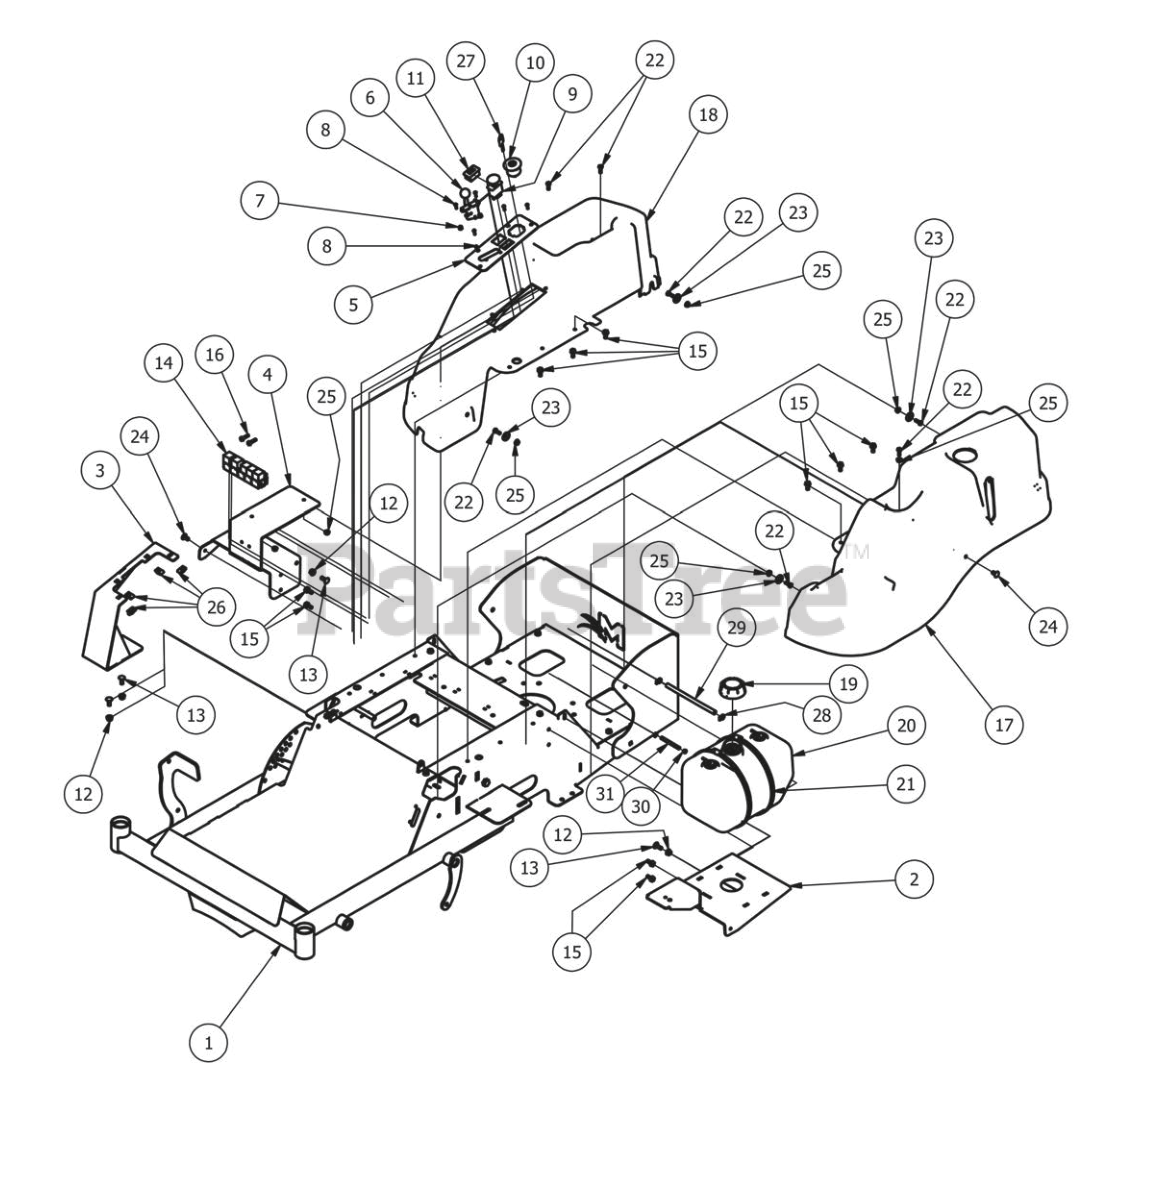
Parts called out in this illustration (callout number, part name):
1	MZ Frame - 2010 MZ
2	MZ Magnum Gas Tank Bracket Assy
3	MZ Magnum Shroud Control Support Assy
4	MZ Magnum Shroud Storage Support Assy
5	Control Panel New MZ
6	Throttle Lever W/Choke
7	10-24 Nylon Insert Locknut
8	10-24 X 5/8 BS C/S 18-8 SS
9	PTO Engager
10	Ignition Switch
11	Tachometer
12	5/16" Nylon Flange Nut
13	5/16" x 7/8" Carriage Bolt
14	Relay Terminal
15	5/16 x 3/4 washer head type F screw
16	1/4 x 1 Hex Head tek screw
17	2013 Magnum Left Fender Shroud
18	2013 Magnum Right Fender Shroud
19	Fuel Cap 2013 Magnum-080165AE
20	2.5 Gal EPA Tank Assy-071145AE
21	MZ Magnum Tank Clamp-63164
22	1/4-20 x 3/4 GR 5 Hex Bolts Zinc
23	.360 ID Plastic Washer
24	Ratchet Fastener
25	1/4-20 Hex Flange Nuts Zinc w/Serrations
26	10-24 "U" Nut
27	Ignition Key
28	1/4 fuel clamp
29	1/4" fuel line hose
30	3/16 vinyl clamp
31	3/16 vinyl tubing
